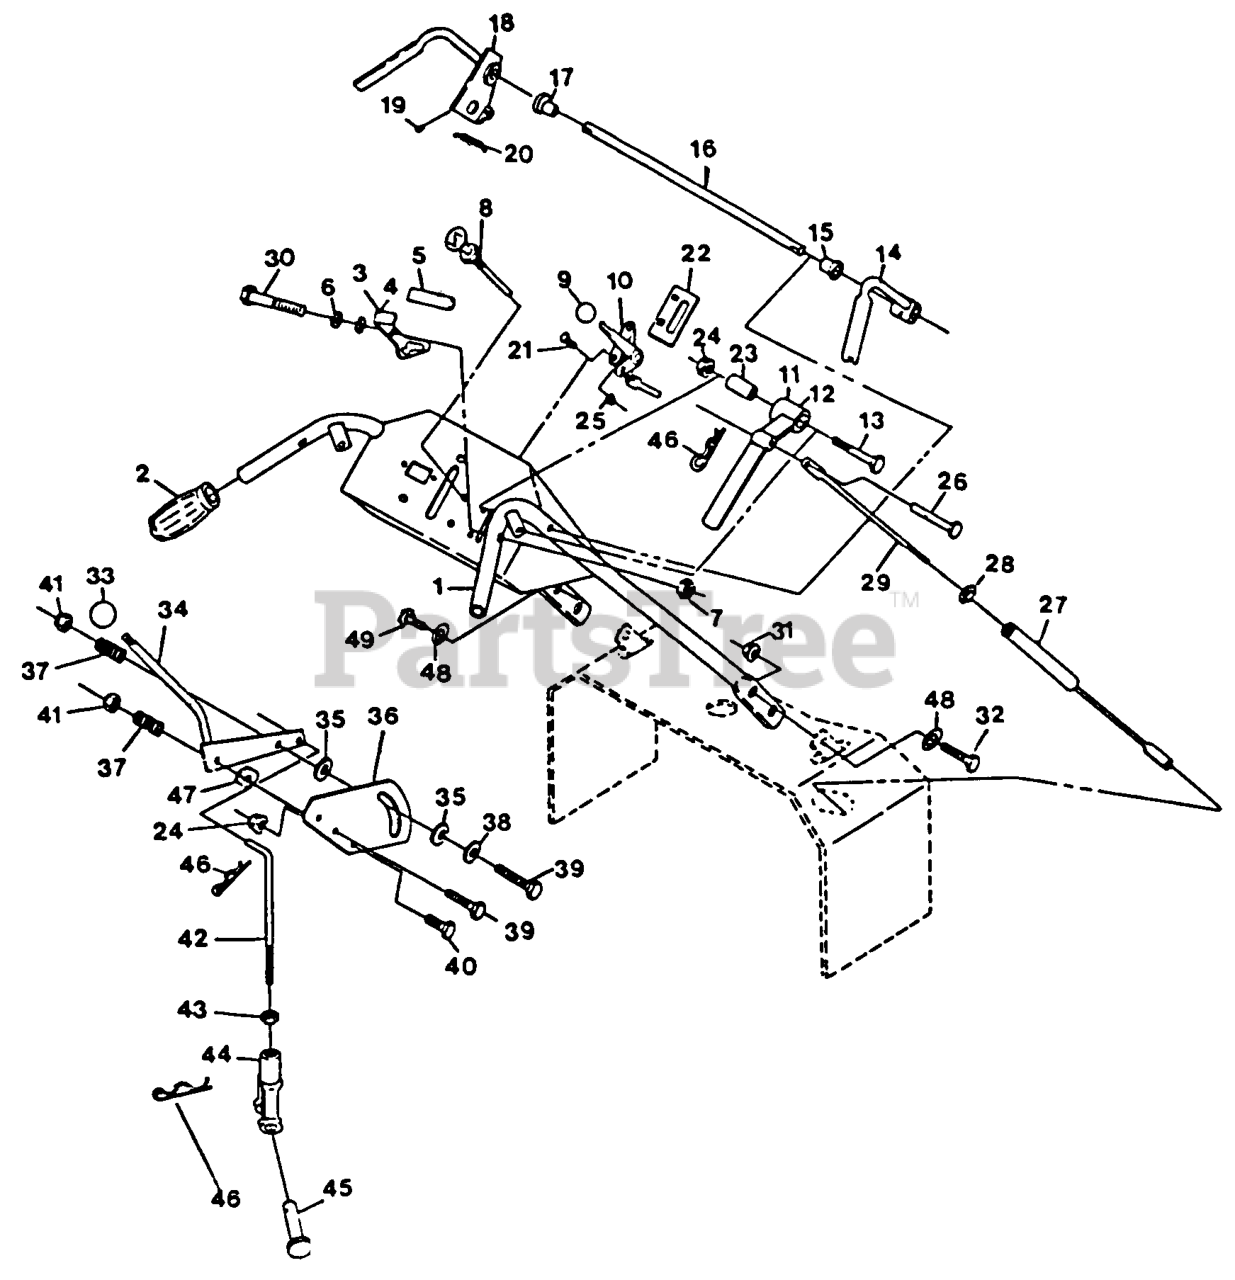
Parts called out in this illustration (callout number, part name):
5	GRIP-LATCH
6	WASHER-SPRING
8	CONTROL-CHOKE
9	KNOB-BALL
15	BUSHING-NYLON
16	ROD,CONNECTING
17	BUSHING,FLANGED
19	SCREW-SET
20	SPRING-EXTENSION
21	BOLT-CARR
22	WASHER-FRICTION
23	BUSHING-LEVER, DRIVE
26	PIN - CLEVIS PLTD
33	KNOB-BALL
36	PLATE-LEVER, SHIFTER
37	SPRING-COMPRESSION
38	WASHER-FRICTION
42	ROD,SPEED CONTROL
44	YOKE-ADJUSTABLE
45	PIN-CLEVIS
46	PIN-COTTER
